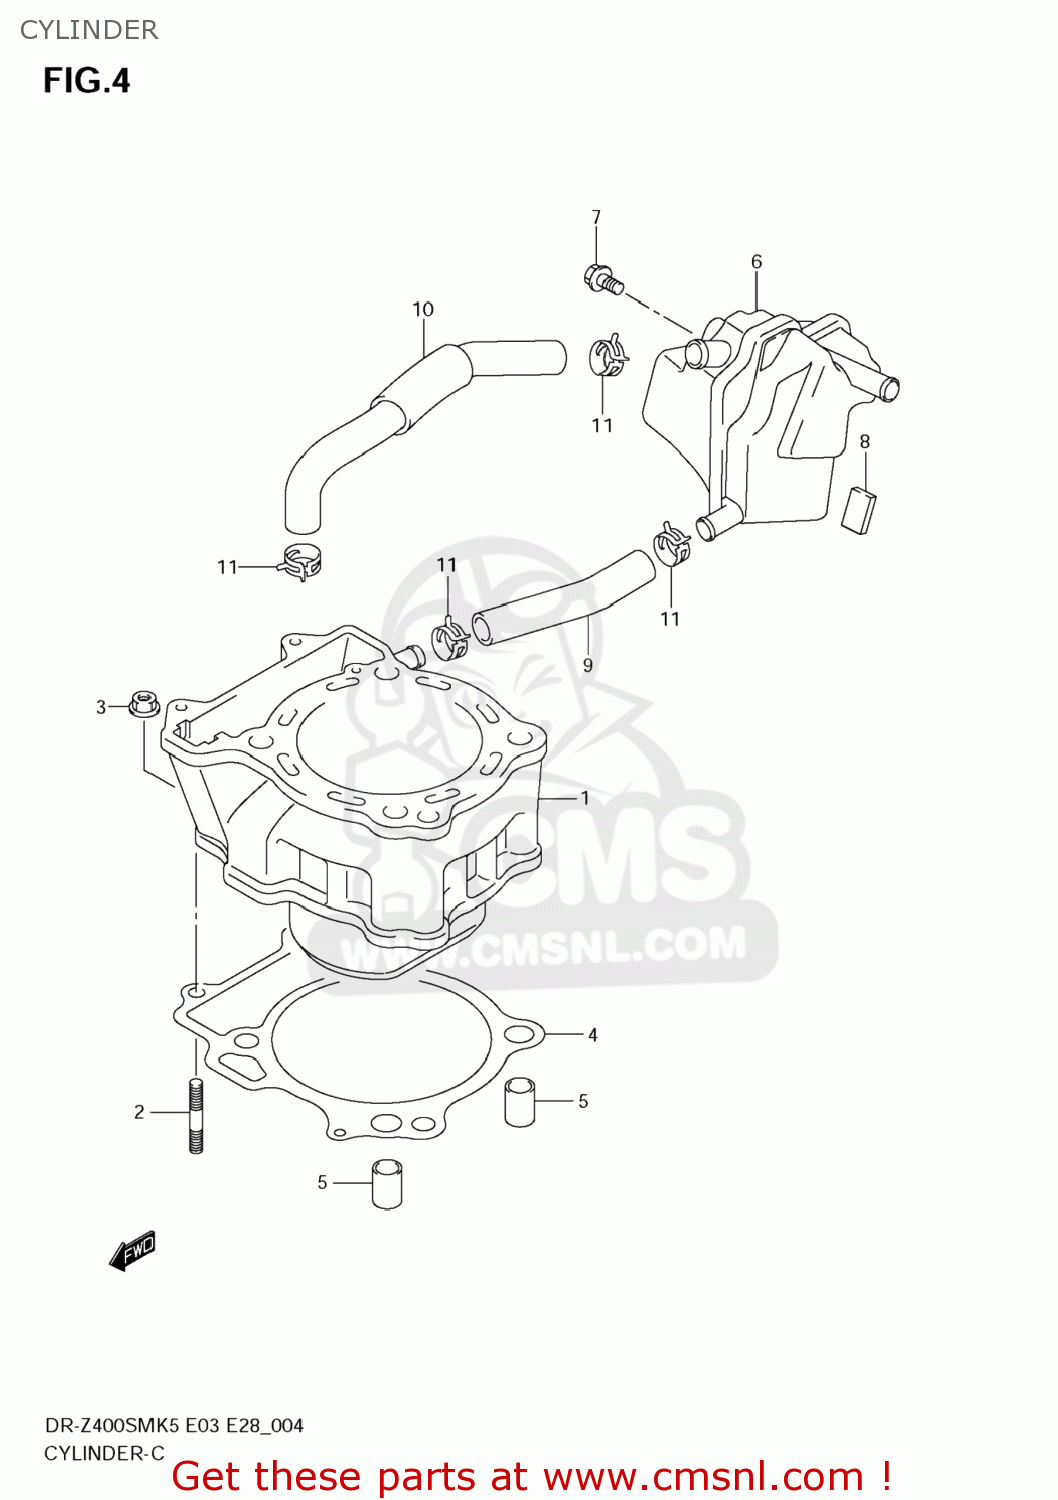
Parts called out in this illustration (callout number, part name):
1	CYLINDER
2	BOLT,STUD
3	NUT
4	GASKET,CYLINDER (NAS)
5	PIN
6	TANK,OIL RETURN
7	BOLT
8	PROTECTOR(170X95X3.0)
9	HOSE,BREATHER
10	HOSE,BREATHER
11	CLIP
